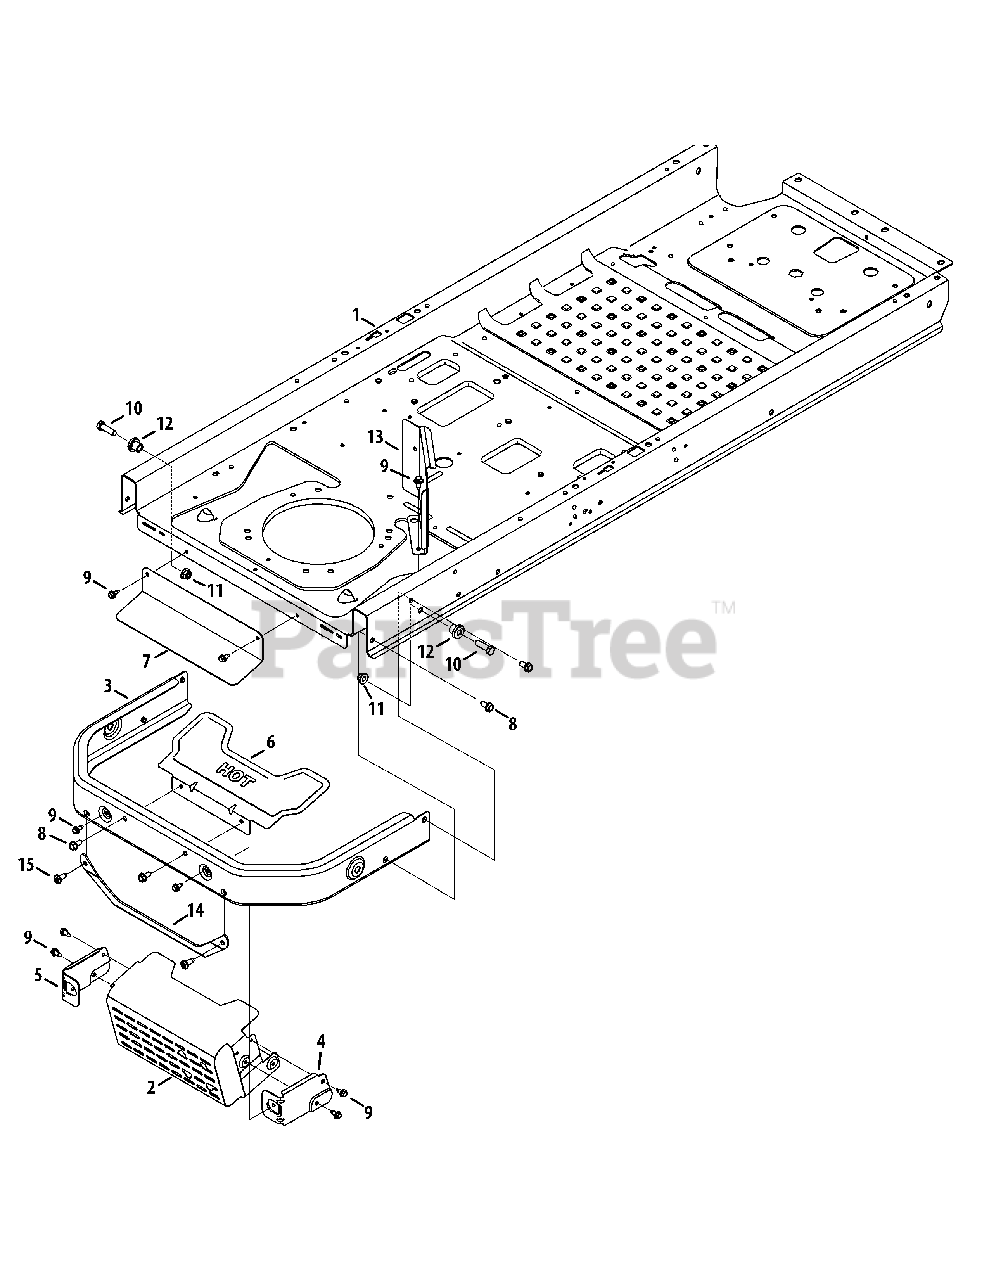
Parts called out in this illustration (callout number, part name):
1	Frame Assembly
2	Muffler Shield Assembly
3	Rear Bumper
4	Muffler Mounting Shield Bracket, RH
5	Muffler Mounting Shield Bracket, LH
6	Muffler Shield
7	Lower Heat Shield
8	Hex Washer Screw, 5/16-18 x .750
9	Hex Washer Screw, 1/4-20 x .625
10	Hex Screw, 3/8-16 x 1.25
11	Flange Lock Nut, 3/8-16
12	Shoulder Spacer, .38 x 1.0 x .70
13	Engine Heat Shield
14	Rear Muffler Shield Bracket
15	Screw, Self-Tapping, 5/16-18, 0.750
